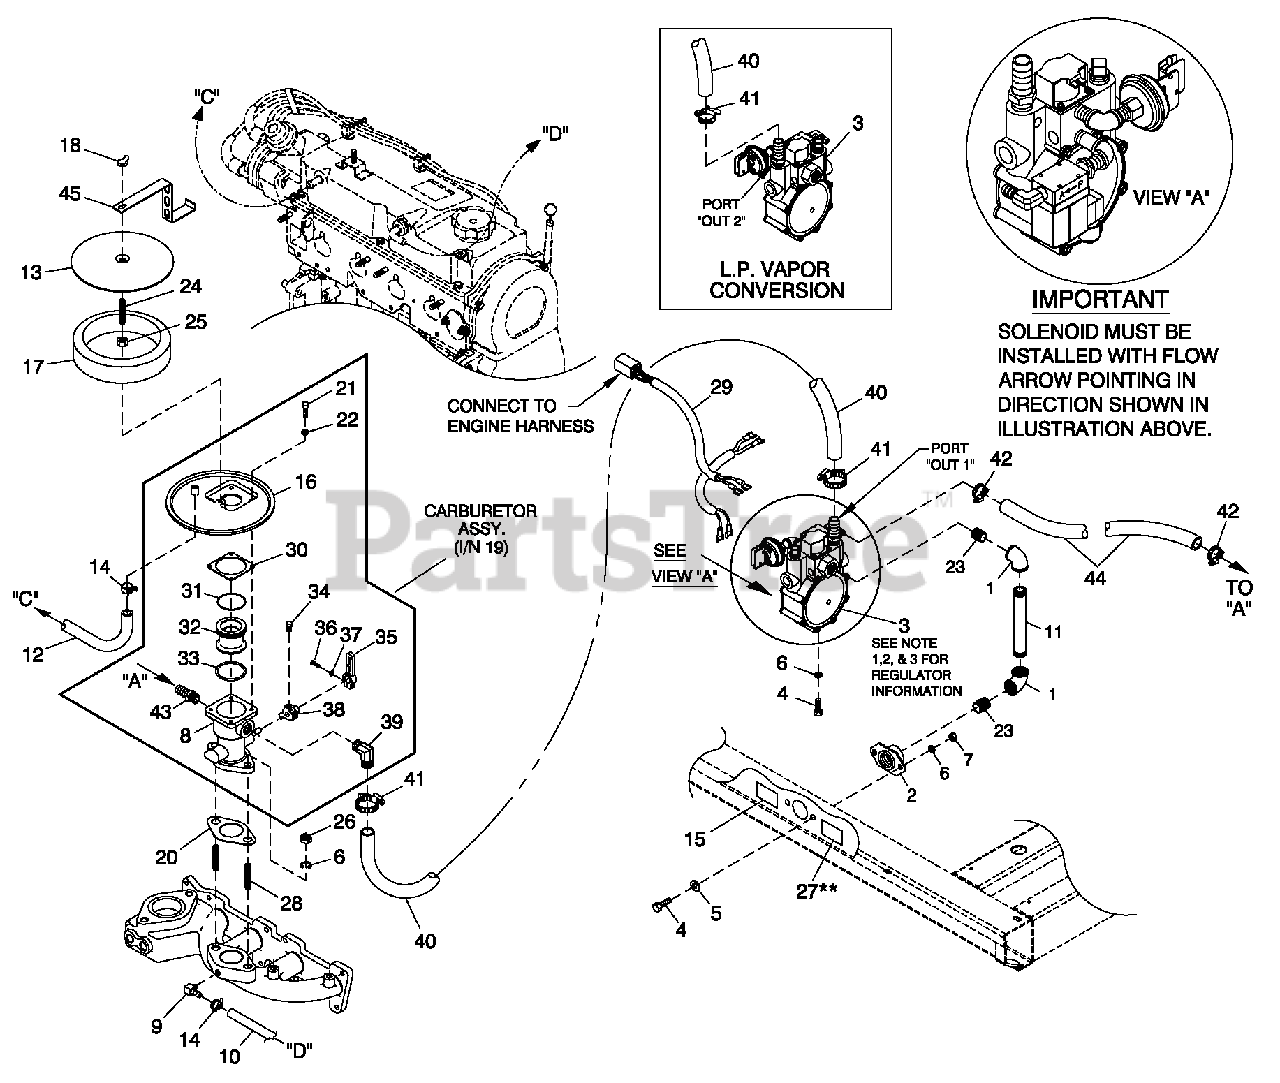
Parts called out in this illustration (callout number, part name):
1	ELBOW 90D 3/4 NPT
2	FLANGE FUEL INLET
3	FUEL RGLTR 1.5L REWORK
4	SCREW HHC M8'1.25 X 20 G8.8
5	WASHER FLAT 5/16 ZINC
6	WASHER LOCK M8'5/16
7	NUT HEX M8'1.25 G8 YEL CHR
8	BODY CARBURETOR ASSEMBLY
9	BARBED EL 90 5/16 X 1/8 NPT
10	HOSE 9/32 ID
11	NIPPLE PIPE 3/4 NPT X 6
12	HOSE CRANKCASE BREATHER
13	COVER AIR CLEANER
14	CLAMP HOSE BAND 1/4
15	DECAL INLET PRESSURE
16	ADAPTER CARB. TO AIR CLNR
17	FILTER ELEMENT
18	NUT WING 1/4'20 NYLK
19	ASSY CARBURETOR 1.5L C1 CPL
20	CARBURETOR GASKET
21	SCREW PPHM M5'0.8 X 12 ZNC
22	WASHER LOCK M5
23	NIPPLE CLOSE 3/4 X 1.375
24	STUD TH 1/4'20 X 3 G2 ZNC FULL
25	NUT HEX 1/4'20 STEEL
26	NUT HEX 5/16'18 STEEL
27	DECAL FUEL INLET NG
28	STUD 5/16'18 X 1.25 F THR
29	HARNESS FUEL JUMPER SINGLE REG
30	GASKET AIR CLEANER ADAPTER
31	O'RING 2'028 1.38 X 1.50 X .06
32	VENTURI 18MM
33	O'RING 29.82 X 2.62
34	SCREW THROTTLE PIN STOP
35	THROTTLE ARM REWORK
36	SCREW HHM #10'32 X 5/8
37	WASHER LOCK #10
38	LEVER THROTTLE STOP
39	BARBED EL 90 3/8 NPT X 5/8
40	HOSE 5/8 ID X 20.5" LG
41	CLAMP HOSE #10 .56 ' 1.06
42	CLAMP HOSE #5.5 .62'.62
43	BARBED STR 1/4 NPT X 1/4 MALE
44	HOSE 1/4 ID SAE 30R7
45	BRACKET'RAD HOSE
